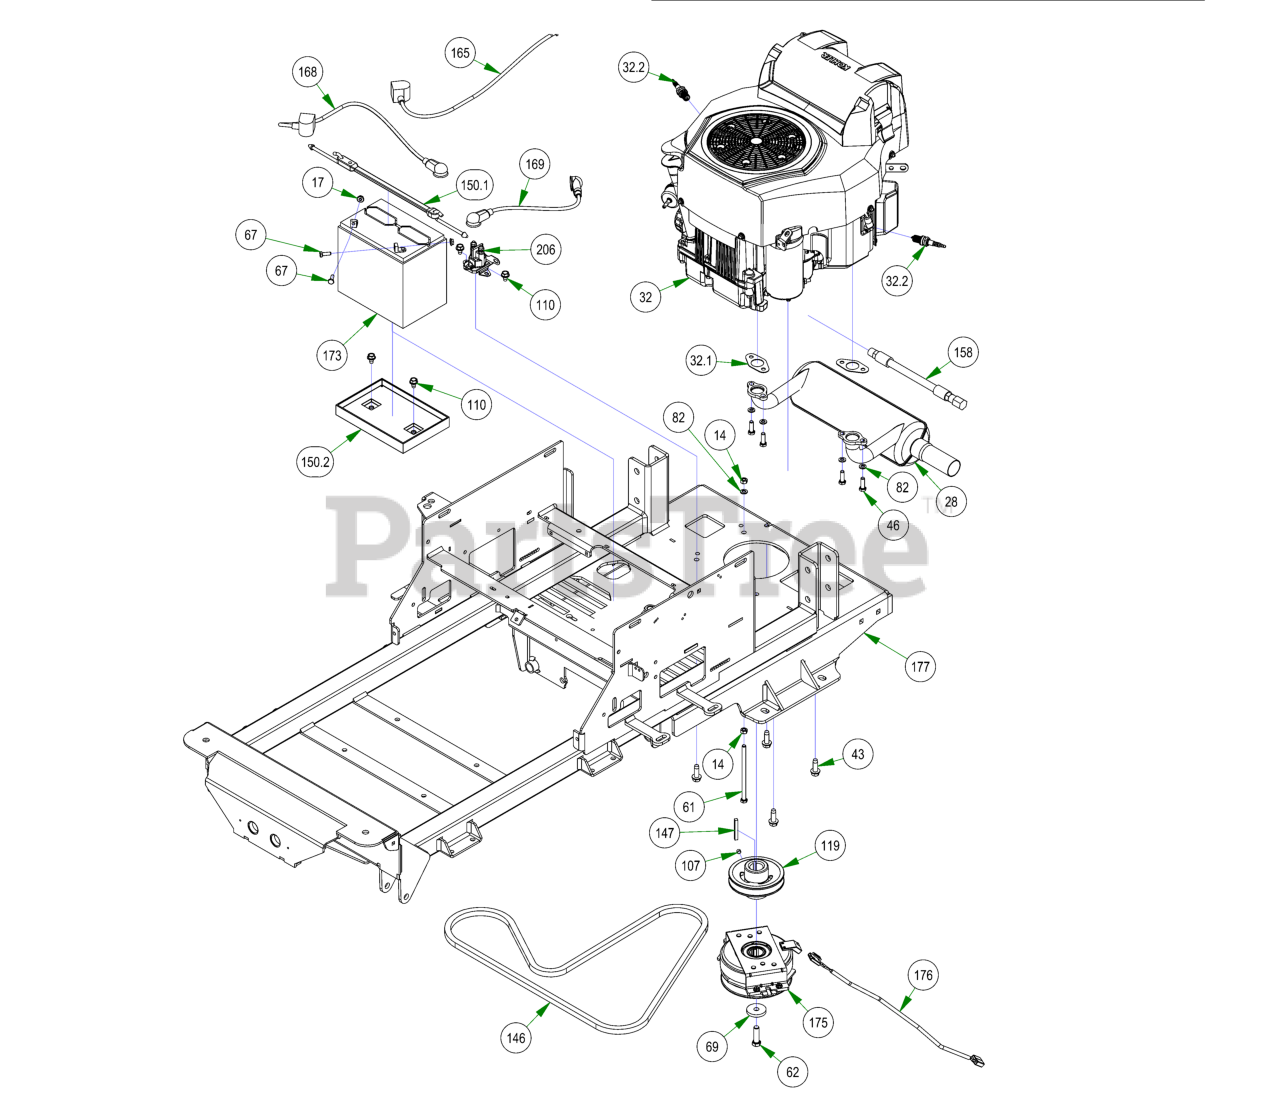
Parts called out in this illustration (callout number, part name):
14	5/16-18 HEX NUT ZINC
17	1/4-20 HEX SERRATED FLANGE NUT HARD/ZINC
28	Kohler Muffler
32	Kohler-2014 CZT/Outlaw 747cc
32.1	Exhaust Gasket
32.2	Spark Plug
43	3/8-16 X 1-1/8 HEX WASHER UNSLOT SERRATED (TRI-LOB) TRS ZINC YELLOW
46	5/16-18 X 1 HEX CAP SCREW (GR.5) ZINC
61	5/16-18 X 5-1/2 HEX CAP SCREW (GR.5) ZINC
62	7/16-20 X 1-1/2 HEX CAP SCREW (GR.8) w/ Patch
67	1/4-20 X 3/4 HEX CAP SCREW (GR.5) ZINC
69	CLUTCH WASHER
82	5/16 SPLIT LOCKWASHER ZINC
107	5/16-24 X 1/4 SOCKET SET SCREW (CUP PT) PLAIN
110	5/16-18 X 1/2 HWH unslot (F) tcs zinc
119	4 3/4 Motor Pulley
146	75.8" Pump Belt
147	1/4 X 2 SQ MACHINERY KEY 1018 STL PLAIN
150	2023 Battery Hold Down Assembly Strap
150.1	2023 Rubber Battery Hold Down Strap
150.2	Battery Tray
158	Oil drain Hose
165	24 inch Black Cable – MZ/ZT
168	24" Red Battery Cable
169	12" Red Battery Cable
173	SP-35 Battery
176	Clutch Pigtail
177	2023 Maverick Frame - Painted
